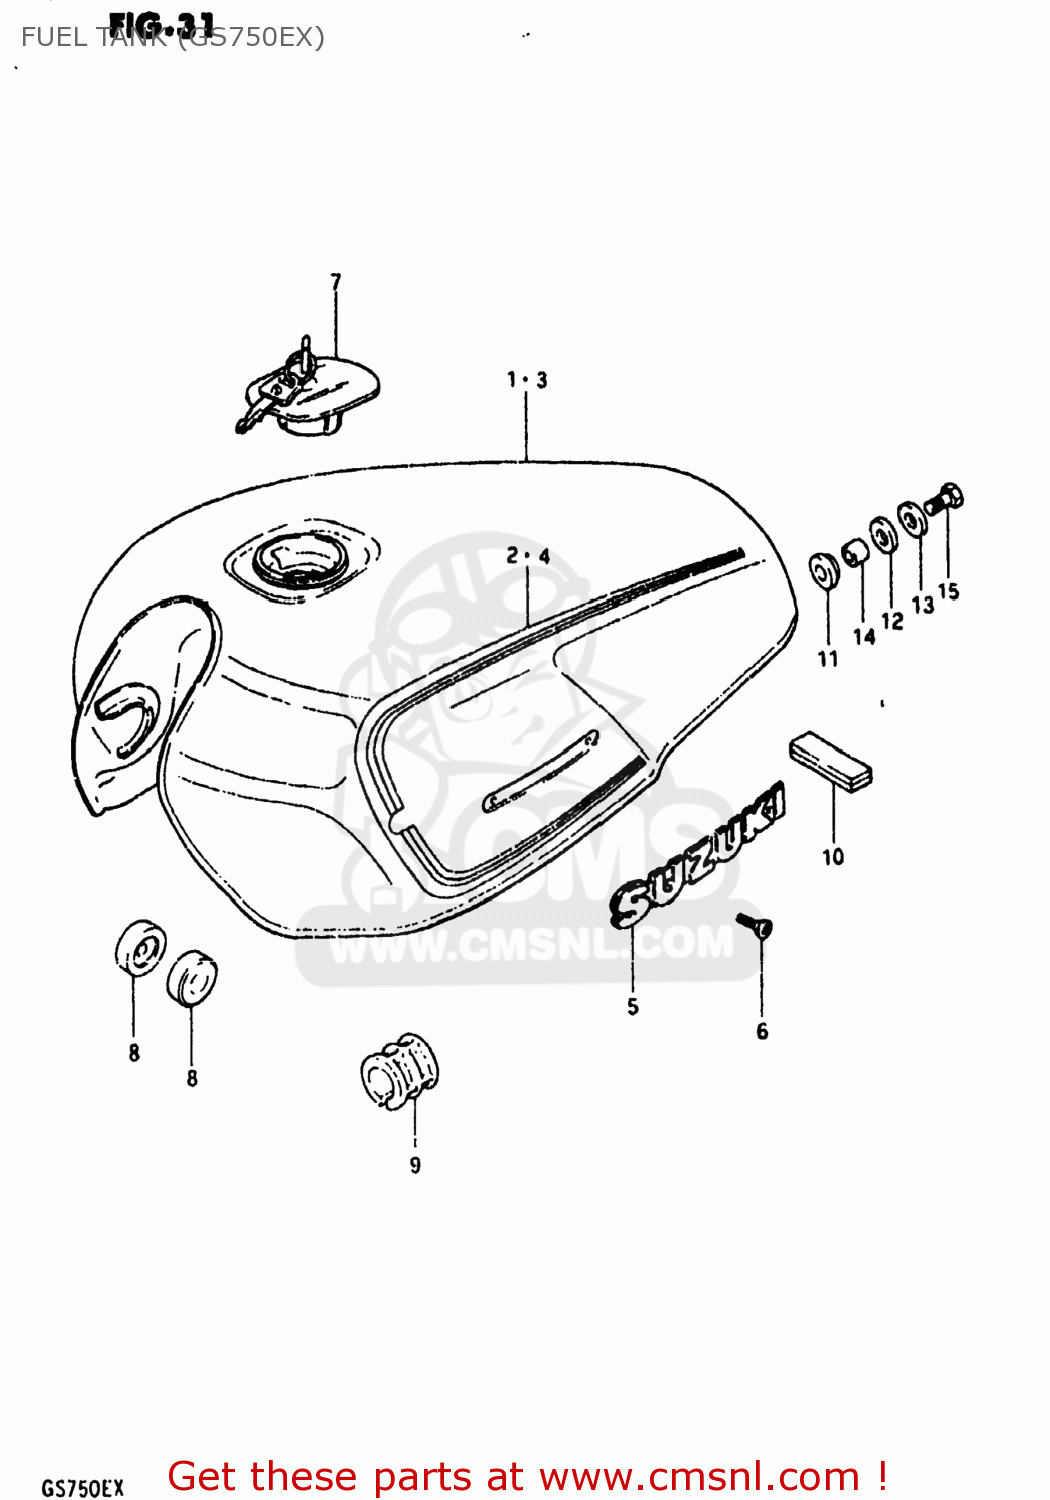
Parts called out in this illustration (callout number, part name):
1	TANK ASSEMBLY,FUEL
2	TAPE SET,FUEL TANK
3	TANK ASSEMBLY,FUEL
4	TAPE SET,FUEL TANK
5	EMBLEM,FUEL TANK
6	SCREW 3X6
7	CAP SET,FUEL TANK
8	CUSHION
9	CUSHION,FUEL TANK,UPPER
10	CUSHION
11	CUSHION
12	CUSHION
13	WASHER (8.5X29X1.6)
14	SPACER(8.5X12X19)
15	BOLT (8X30)
